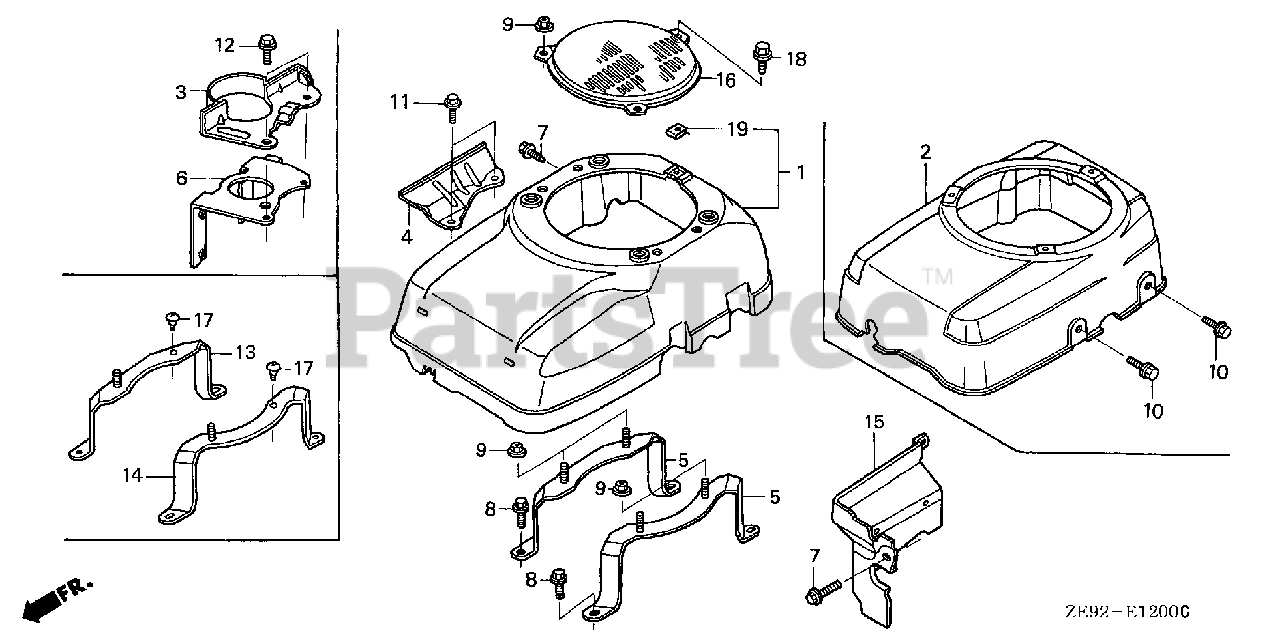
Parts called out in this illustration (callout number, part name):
1	COVER, FAN *R8* (BRIGHT RED)
1	COVER, FAN *NH1* (BLACK)
1	COVER, FAN *R280* (POWER RED)
5	BRACKET, FAN COVER
7	BOLT, FLANGE (6X12) (CT200)
8	BOLT, FLANGE (6X16) (CT200)
9	NUT, FLANGE (6MM)
